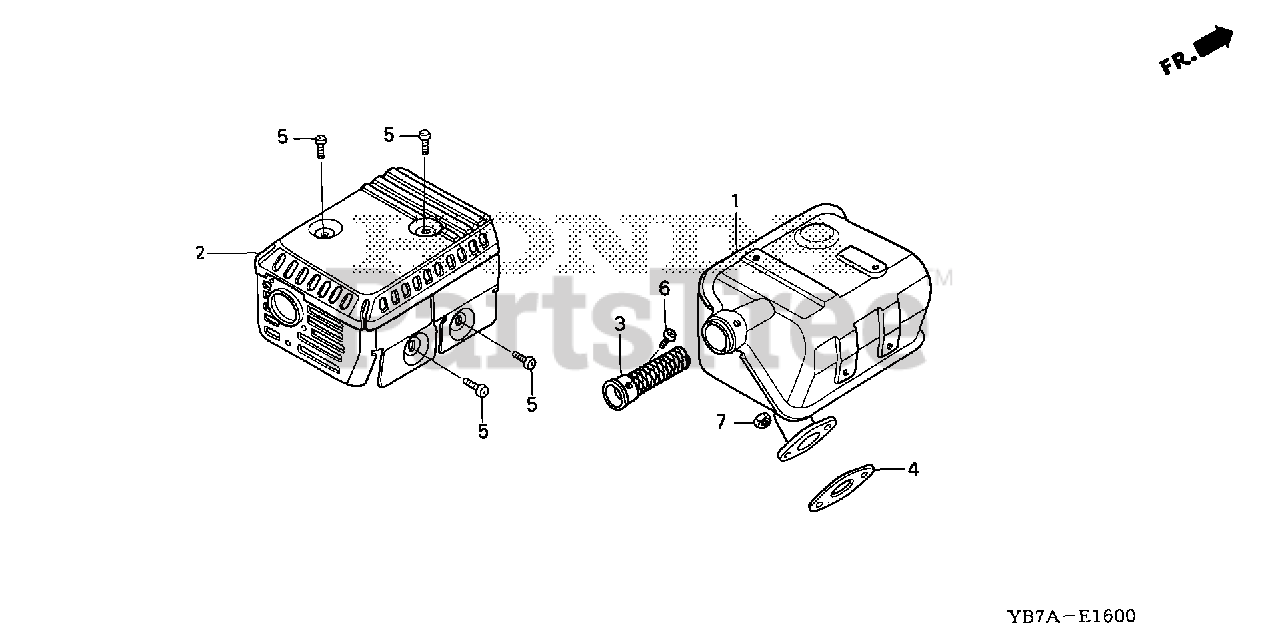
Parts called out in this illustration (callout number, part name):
1	MUFFLER (ARRESTER)
2	PROTECTOR, MUFFLER (STD)
3	ARRESTER, SPARK
4	GASKET, MUFFLER
5	SCREW, TAPPING (5X8)
6	SCREW, TAPPING (4X6)
7	NUT, HEX. (8MM)
